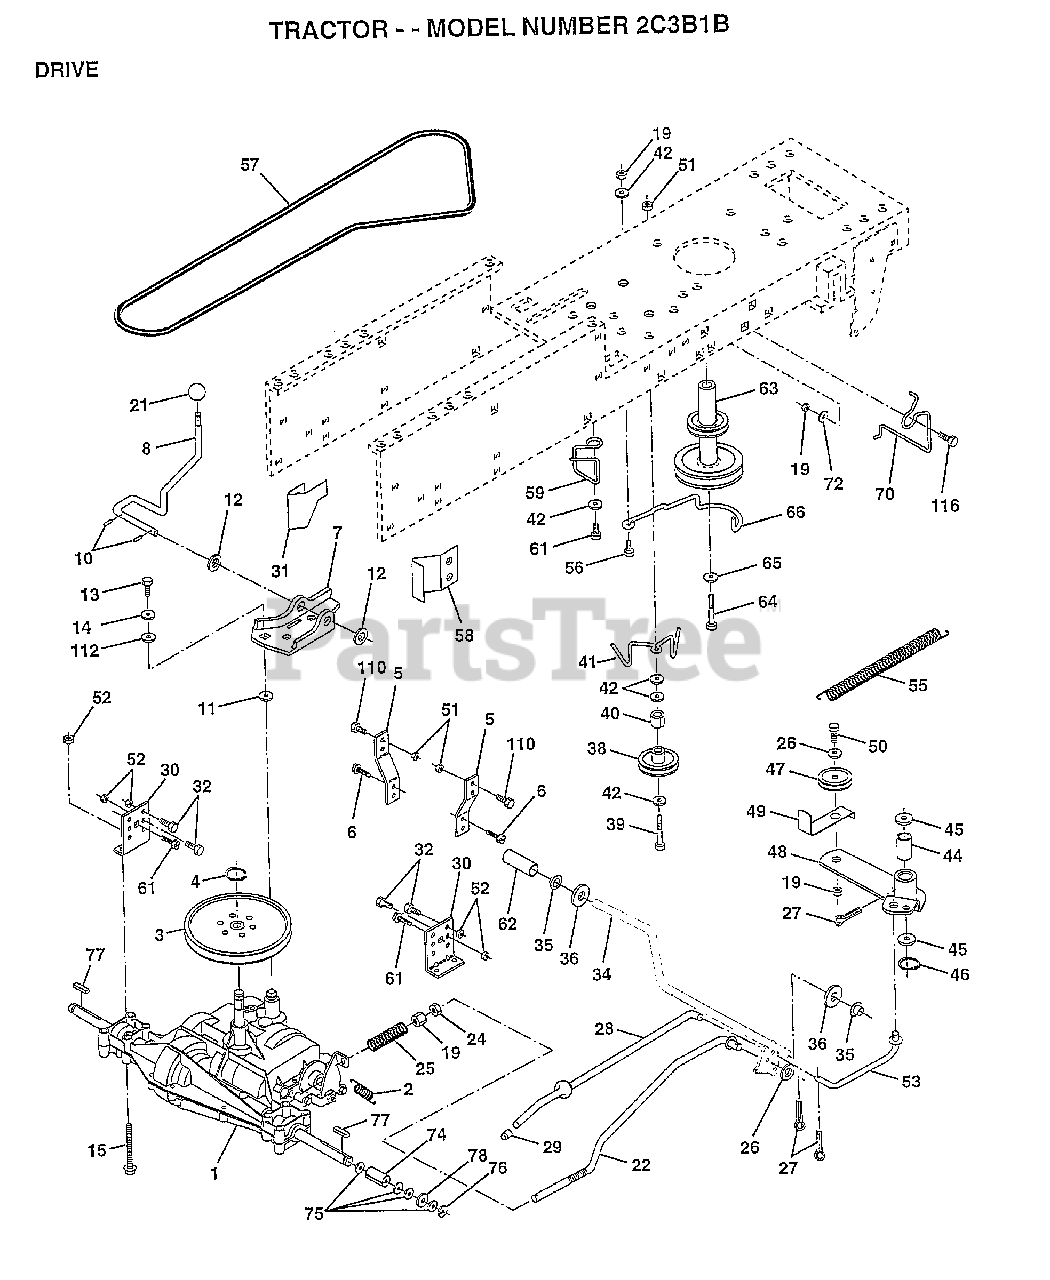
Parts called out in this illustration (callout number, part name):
2	SPRING.BRAKE.RETU
3	PULLEY TRANS
5	STRAP TORQUE
6	SCREW
8	SHIFT ROD
10	PIN COTTER 1/8
11	WASH-SHFT PLT LT
12	WASHER
13	BOLT.1/4-28.W/PAT
14	LOCKWASHER
15	BOLT.HX.FLG.5/16
19	NUT
21	KNOB T (1/2-HOLE)
22	BRAKE ROD
24	NUT
25	SPRING ROD LT
26	WASHER
27	COTTER PIN
28	ROD.BRAKE.PARK.LT
29	PLUNGER CAP T
30	TRANSAXLE MTG BKT
31	"KEEPER,BELT LH T"
32	BOLT
34	SHAFT FOOT PEDAL
35	NYLON BEARING
36	WASHER LT
38	PULLEY.IDLER.FLAT
39	BOLT
40	SPACER T
41	KEEPER BELT
42	WASHER
44	"LY, BEARING"
45	WASHER LT
46	KLIP RING
48	ARM IDLER
49	RETAIN BELT
53	"LINK, CLUTCH T"
55	"SPRING, RETURN LT"
58	"KEEPER,BELT RH T"
59	KEEPER BELT CNTSP
61	SCREW
62	PEDAL COVER T
63	PULLEY.ENGINE
64	BOLT
65	LOCKWASHER
70	KEEPER BELT ENG
72	WASHER
74	SPACER LT
76	E-RING LT
77	SQUARE KEY
78	WASHER
112	WASHER LT
116	BOLT RDHD 3/8-16
